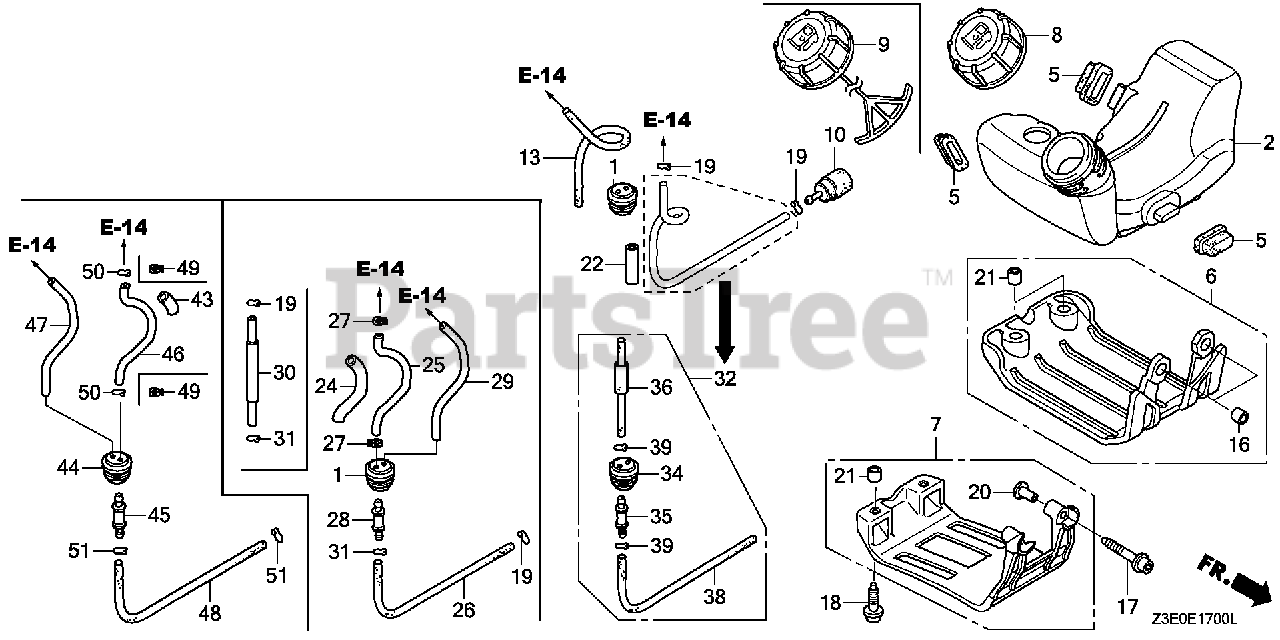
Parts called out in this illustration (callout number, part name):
1	GROMMET, FUEL TUBE
2	TANK, FUEL (FOR U.S.A.)
5	RUBBER, TANK MOUNTING
6	GUARD, TANK *T93* (HUSQVARNA ONLY) (HUSQVARNA GRAY)
9	CAP ASSY., FUEL TANK
10	FILTER, FUEL
13	TUBE, FUEL RETURN
16	COLLAR, FR. TURN SIGNAL
18	BOLT, SOCKET (5X16)
19	CLIP, TUBE
21	COLLAR A, HEAD COVER
22	PROTECTOR, TUBE
26	TUBE A, FUEL
28	FITTING
29	TUBE, FUEL RETURN
30	TUBE, FUEL FEED
31	CLIP, TUBE
32	GROMMET ASSY., FUEL TANK
34	GROMMET, FUEL TUBE
35	FITTING
36	TUBE, FUEL FEED
38	TUBE A, FUEL
39	CLIP, TUBE
43	PROTECTOR, TUBE
44	GROMMET, FUEL TUBE
45	FITTING
46	TUBE, FUEL FEED
47	TUBE, FUEL RETURN
48	TUBE A, FUEL
50	CLIP, TUBE (B1 5)
51	CLIP, TUBE (B1 5)
